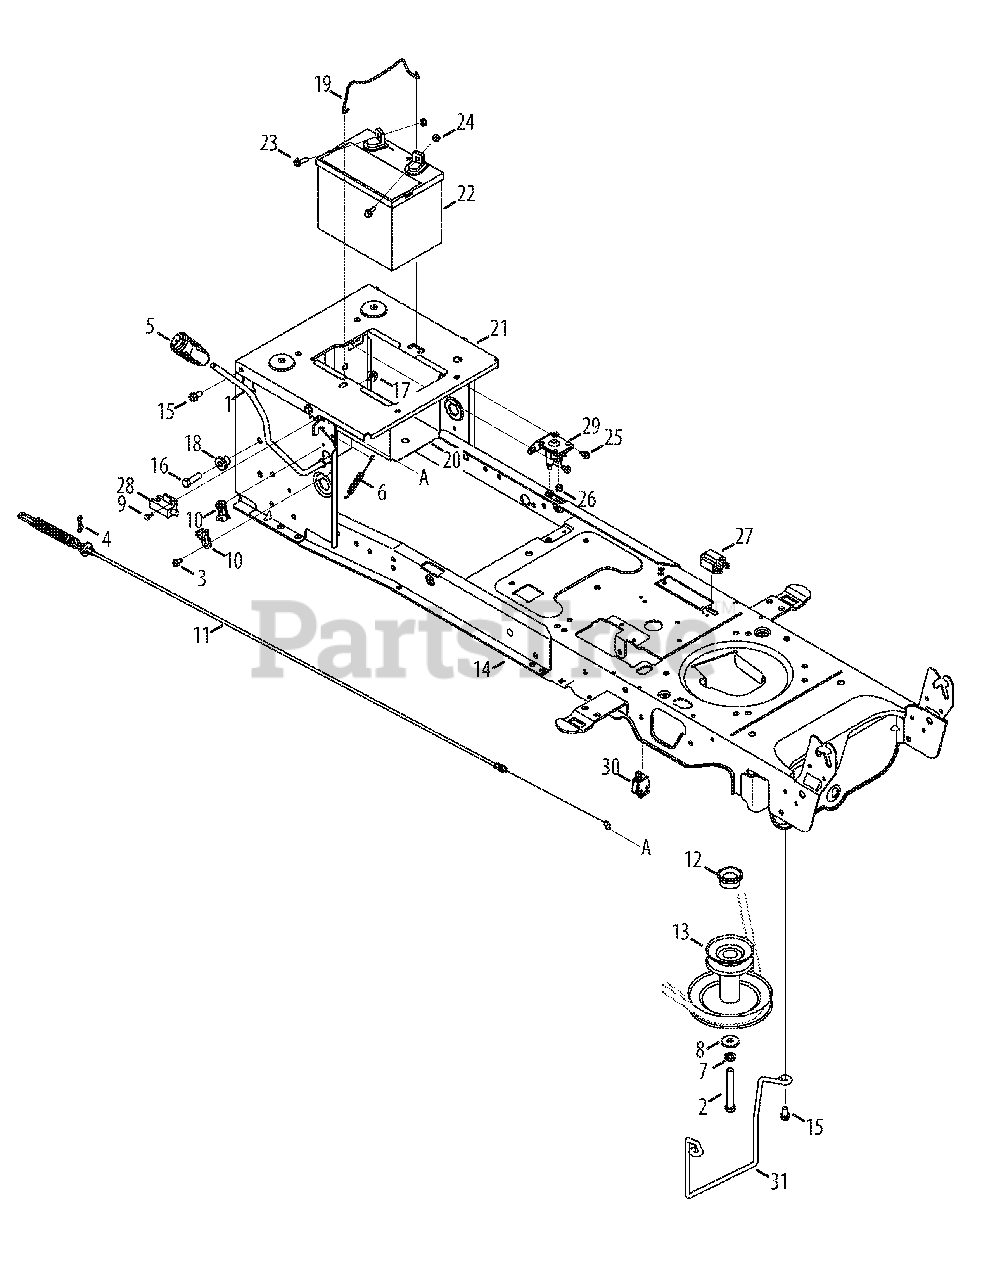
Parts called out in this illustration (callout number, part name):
1	Handle Ass’y, PTO
2	Hex Screw, 7/16-20, 3.50, Gr5
3	Screw, Self-tapping, 1/4-20, 0.50
4	Pin, Cotter, Bow-Tie 72
5	Grip, Handle, 3/8
6	Spring, Ext, .38 Dia x 5.6
7	Washer, Lock, 7/16, Regular Duty
8	Washer, Flat, .450 x 1.250 x .164
9	Screw, Shoulder, #10-32, .500
10	Bearing, PTO
11	Cable, Engag, Deck
12	Spacer, 1.010 x 1.400 x .825
13	Pulley, Engine, 3.56 x 6.12 Dia.
14	Frame Ass’y, Lower
15	Screw, Self-tapping, 5/16-18, .750,
16	Hex Screw, 3/8-16, 1.25, Gr5, Std
17	Nut, Flange Lock, 3/8-16, Grf,
18	Spacer, Shoulder, .38 x 1.0 x .70
19	Rod, Battery
20	Tray, Battery
21	Bracket, Frame, Seat
22	Battery
23	Hex Flange Screw, 1/4-20, .75, Gr5
24	Nut, Sems, 1/4-20
25	Screw, Self-tapping, 1/4-20, 0.375,
26	Nut, Flange Lock, 1/4-20, Grf,
27	Switch, 3-Pole
28	Switch, Interlock
29	Solenoid, 12V
30	Switch, Plunger, Snap Mount
31	Belt Keeper Rod
